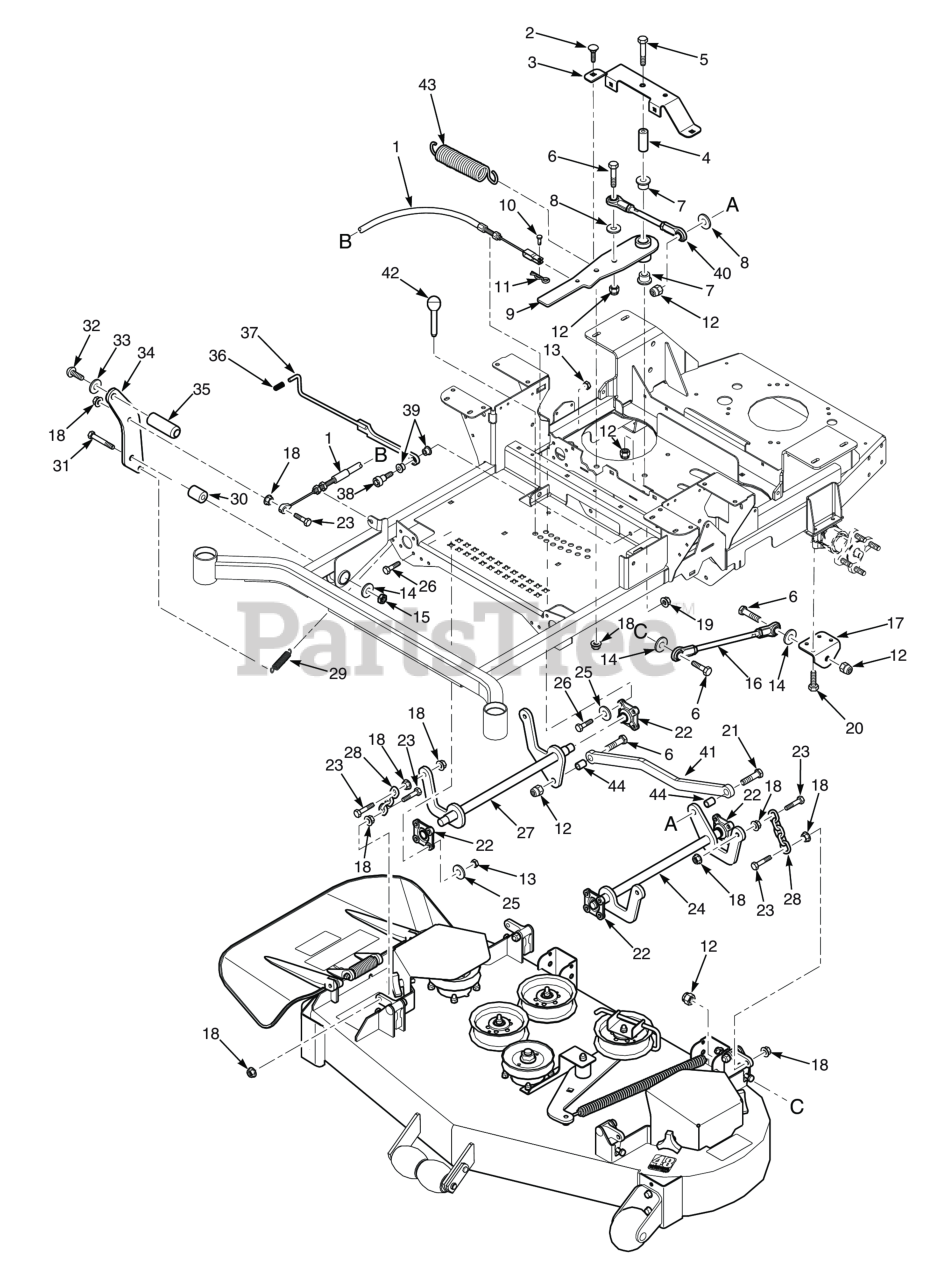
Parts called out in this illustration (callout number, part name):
1	Cable, Deck Lift
2	Bolt, Carriage 3/8-16 x 3/4"
3	Support, Idler Arm
4	Spacer, Deck Lift Pivot
5	Bolt, Hex Head, 1/2-13 x 3-1/4"
6	Hex Head Bolt, 1/2-13 x 2"
7	Bearing, Plastic
8	Flatwasher, 1/2 - .531 x 1.062 x .095
9	DECKLIFT BELLCRANK ASSY, SFZ
10	Clevis Pin, 5/16 x 3/4"
11	COTTER PIN, HAIR - 0.94 X 1.62
12	HEX LOCKNUT, ELASTIC STOP, 1/2-13
13	Nut, Flange Head Elastic Stop 5/16-18
14	Flat Washer, 1/2 (.562 x 1.375 x .109)
15	HEX NUT, ELASTIC STOP LOCK, 3/8-16
16	Linkage, Push Arm
17	Bracket, Push Arm Link
18	NUT, 3/8-16 SERRATED FLANGE HEX HEAD
19	HEX NUT, ELASTIC STOP LOCK, 3/8-16
20	Bolt, Hex Head 5/16-18 x 3.00"
21	Bolt, Hex Head 1/2-13 x 3"
22	Bearing, Deck Lift - 48V & 52V
23	Bolt, Hex Head 3/8-16 x 1-1/2" B&S 32BV
24	Weldment, Deck Lift LH
25	Flatwasher, 1/4" (.312 x .750 x .065")
26	Bolt, Heax Head 5/16-18 x 1" (48V / 52V)
27	Weldment, Deck Lift RH
28	Chain, Deck Lift
29	Spring, Deck Lift
30	Spacer, Deck Lift Pivot
31	Bolt, Hex Head 1/2-13 x 3"
32	Bolt, Head Socket 5/8-11 x 1-1/2"
33	Lockwasher, 5/8" Spring
34	Pedal, Foot Bracket
35	Foot Pedal, Height Adjustment
36	Grip, Deck Latch
37	Weldment, Deck Latch
38	Bolt, Shoulder 1/2 x 1/2"
39	Bearing
40	Linkage Assembly, Deck Lift
41	Mounting Bracket, Fuel Tank Front
42	Pin, Height Adjuster
43	Spring, Deck Lift
44	Sleeve
